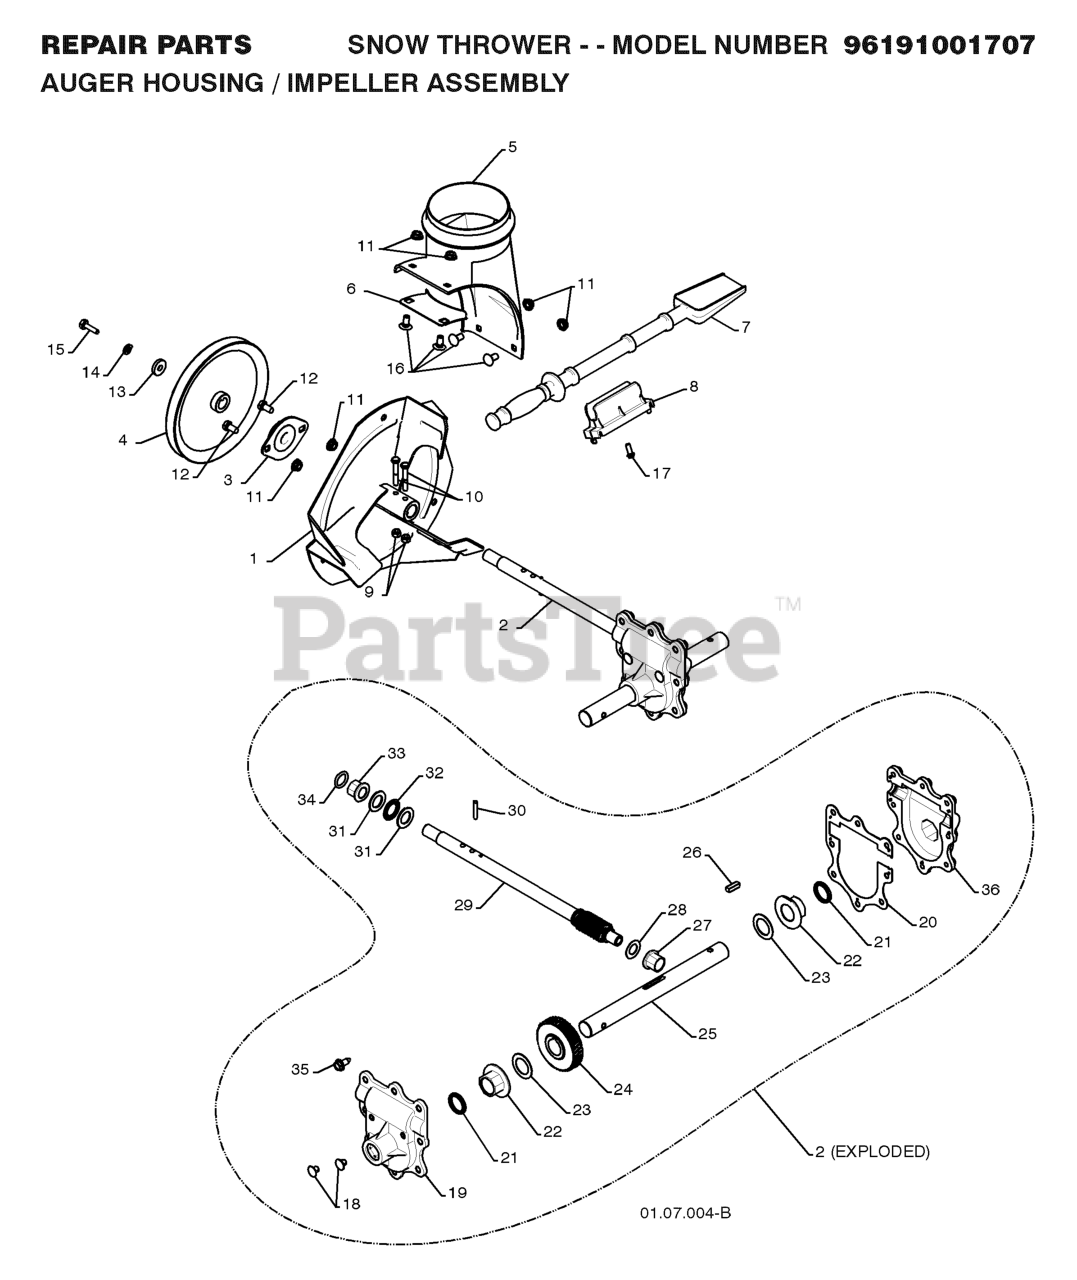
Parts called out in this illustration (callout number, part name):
1	IMPELLER ASSY
2	GEARBOX.ASSEMBLY.AUGER
3	BEARING FLANGE
4	PULLEY, IMPELLER
5	BASE DISCHARGE CHUTE
6	BRACKET, CORNER DISCHARGE
7	CLEAN OUT TOOL
8	CLIP.CLEANOUT.TOOL
9	LOCKNUT.NYLOC.1/4-20
10	SCREW.HEX.HD1/4-20X
11	NUT.FLANGE.5/16
12	BOLT, HEX HEAD 5/16-18
13	WASHER, FLAT
14	WASHER.LOCK.HVY.HLCL.SPR.5/16
15	CAPSCREW.HX.HD.5/16-18X1.00.NY
16	BOLT.CARRIAGE.5/16-18X
17	SCREW.HWH.13-16-5.8.BZP
18	CASE PLUG
19	GEARBOX HOUSING-RH
20	GEARBOX GASKET
21	OIL SEAL
22	FLANGE BUSHING-1"
23	WASHER TRUST 1"
24	WORM GEAR
25	AUGER SHAFT
26	KEY, SQUARE 1/4 X .875
27	FLANGE BUSHING-5/8
28	WASHER, THRUST 5/8
29	SHAFT, IMPELLER
30	PIN, ROLL 3/16 X 1-1/8
31	WASHER, THRUST 3/4
32	BEARING TRUST 3/4 NTA-1220
33	BUSHING, FLANGE 3/4
35	HEX SCREW-5/16 X 3/4
36	HOUSING.GEARBOX.LH(SERVICE)
